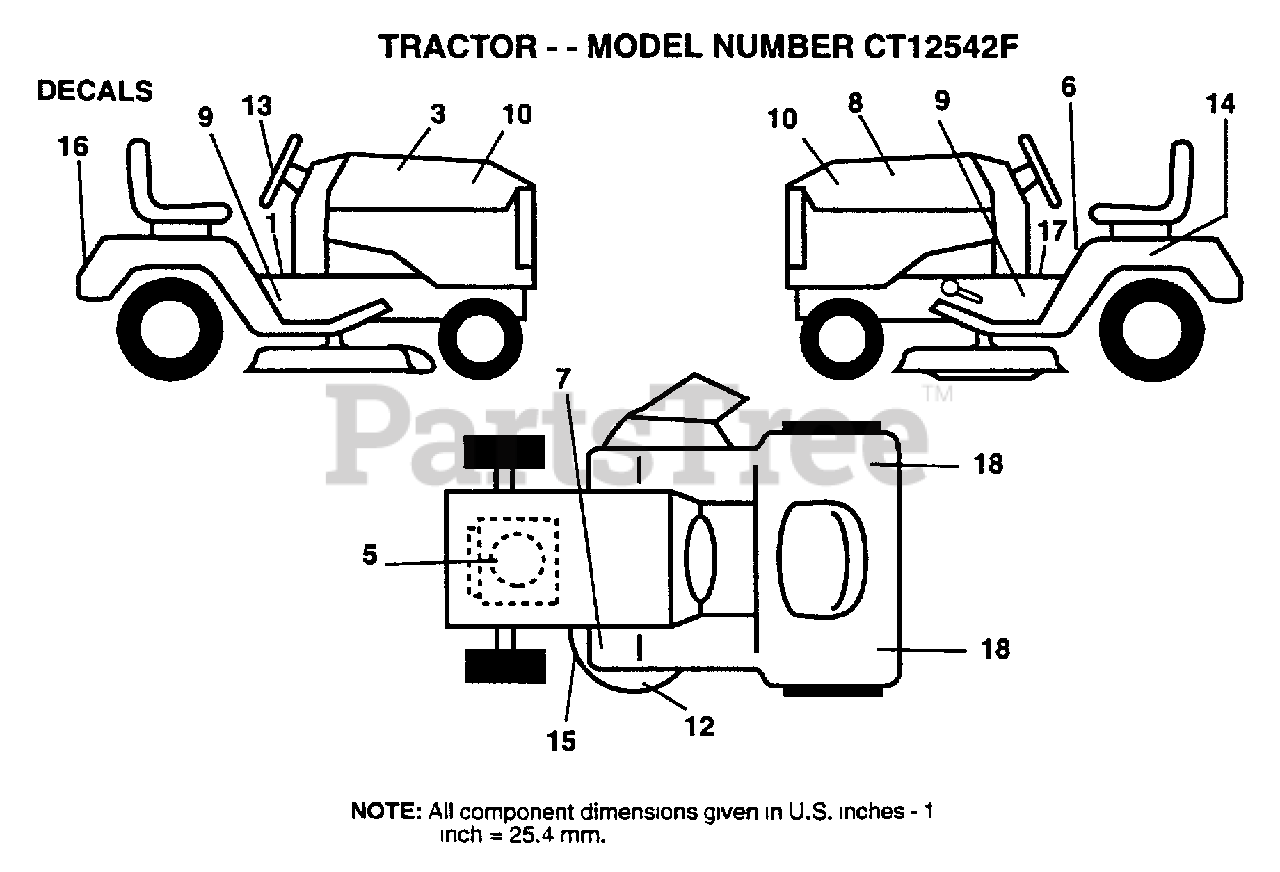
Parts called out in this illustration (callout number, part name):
3	DECAL.HD.RH.RALLY
5	DECAL.ENG.272632
6	DECAL
8	DECAL.HD.LH.RALLY
9	CHASSIS DECAL
10	"DECAL, HP HOOD"
13	DECAL INST STRWHL
14	DECAL
15	DECAL
16	DECAL.FENDER
17	DECAL BRAK PARK
18	REFLECTOR-TAIL YT
